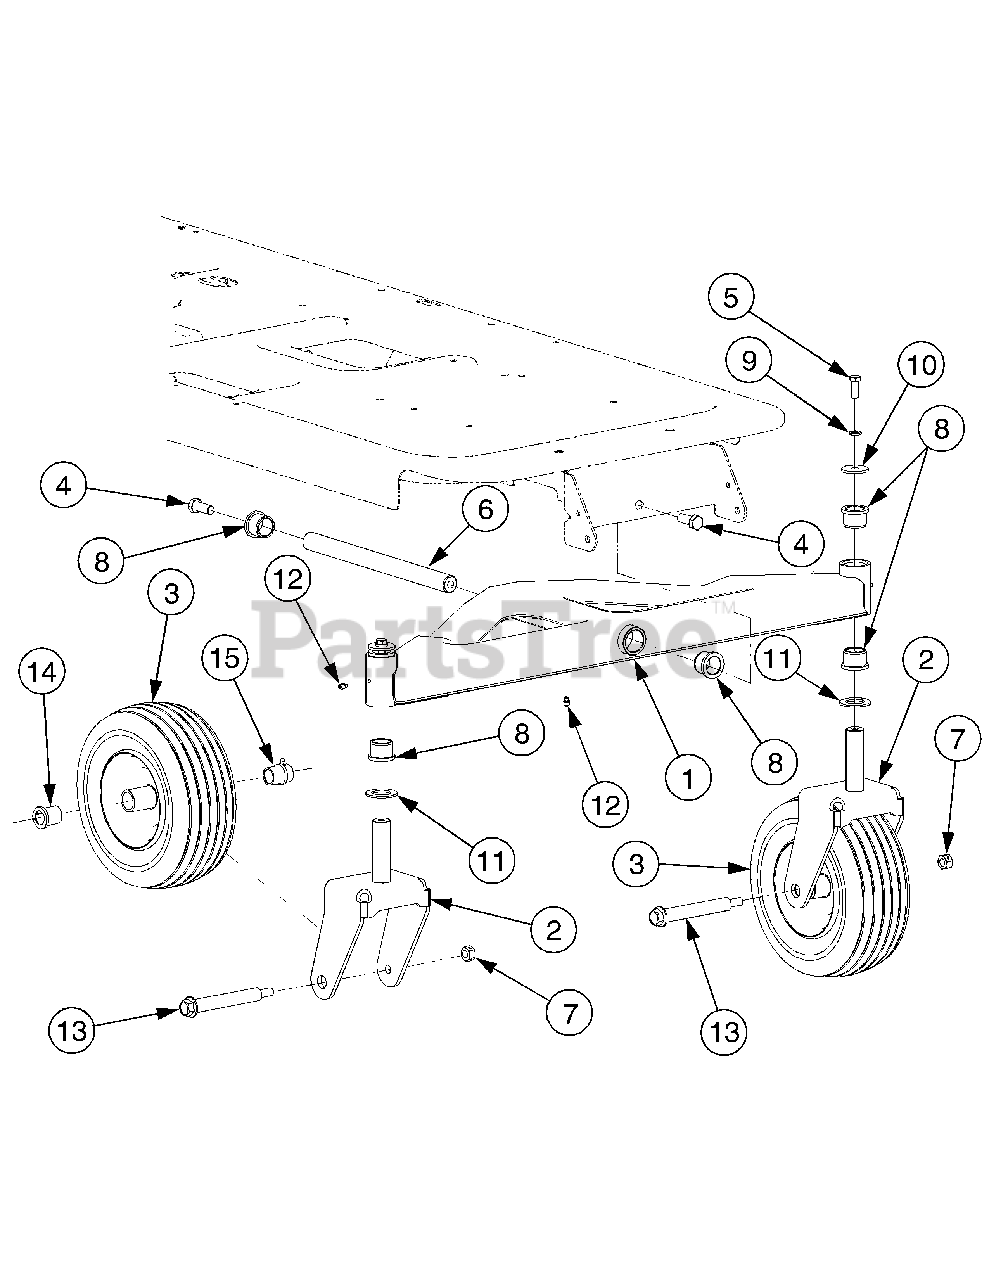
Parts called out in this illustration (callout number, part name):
3	Wheel Assembly, 11.0 x 4.0 x 5.0
4	Screw, Hex Lock, 1/2-13 x 1.25 GR5
5	Screw, Hex Cap, 3/8-16 x 1.0 GR5
6	Shaft, Axle
7	Nut, Hex Lock, 1/2-13 GRB
8	Bearing, Flange, 1.0 x 1.246
9	Washer, Lock, 3/8
10	Washer, Flat, .39 x 1.5 x .134
11	Washer, Flat, 1.0 x 1.75 x .107
12	Fitting, Lube, 3/16 Drive
13	Screw, Shoulder, .75 x 4.75:7/16-14
14	Bearing, Flange, .76 x 1.0 x 1.2
15	Bearing, Flange, .76 ID w/Lube Ftg.
